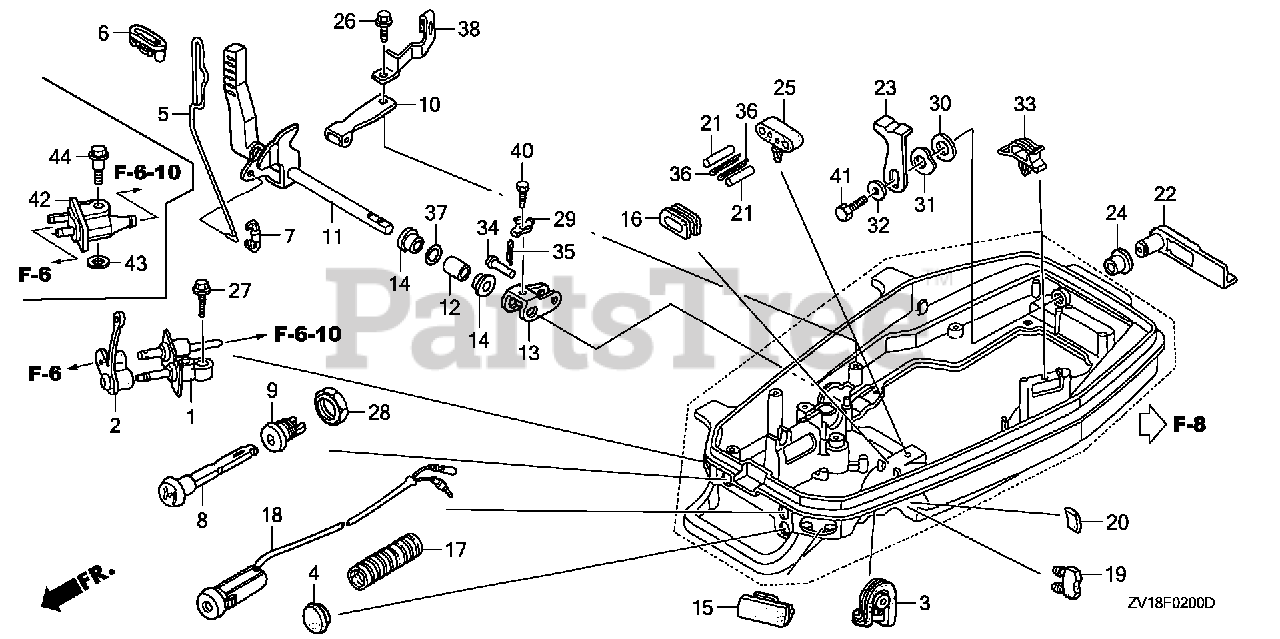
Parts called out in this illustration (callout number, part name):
1	CONNECTOR, FUEL *NH282MU* (OYSTER SILVER METALLIC-U)
2	CAP, FUEL JOINT
3	GROMMET, THROTTLE CABLE
4	GROMMET B, CASE (LOWER)
6	BUSH, CAM ROD
7	BUSH, LINKAGE
8	KNOB, CHOKE
9	GUIDE, CHOKE KNOB
10	SPRING, CLICK
11	SHAFT, SHIFT
12	COLLAR, SHIFT SHAFT
13	ARM, SHIFT
14	BUSH, SHAFT
15	GROMMET A, CASE (LOWER)
16	GROMMET B, ALTERNATOR WIRE
17	TUBE, WIRE CLAMP
18	LAMP ASSY., INDICATOR
19	RUBBER C, MOUNTING
20	RUBBER, DAMPER
21	PIN, SHEAR
22	LEVER, COVER LOCK *NH282MU* (OYSTER SILVER METALLIC-U)
23	HOOK, COVER LOCK
24	BUSH, COVER LOCK
25	HOLDER, PARTS
26	BOLT, FLANGE (6X12) (CT200)
27	BOLT, FLANGE (6X20)
28	NUT, HEX. (16MM) DUAL QTY = (2) (SINGLE)
29	WASHER, TONGUED
30	WASHER (14MM)
31	WASHER, WAVE (14MM)
32	WASHER (6MM)
33	CLIP, CABLE
34	PIN (5X34)
35	PIN, COTTER (1.6MM)
36	PIN, COTTER
37	O-RING (9.8X2.4)
38	CLIP, TUBE
40	BOLT, HEX. (5X16)
41	BOLT, HEX. (6X16)
42	CONNECTOR ASSY., FUEL (B)
43	WASHER, PIVOT
44	BOLT, SPECIAL (6X22) (CT200)
